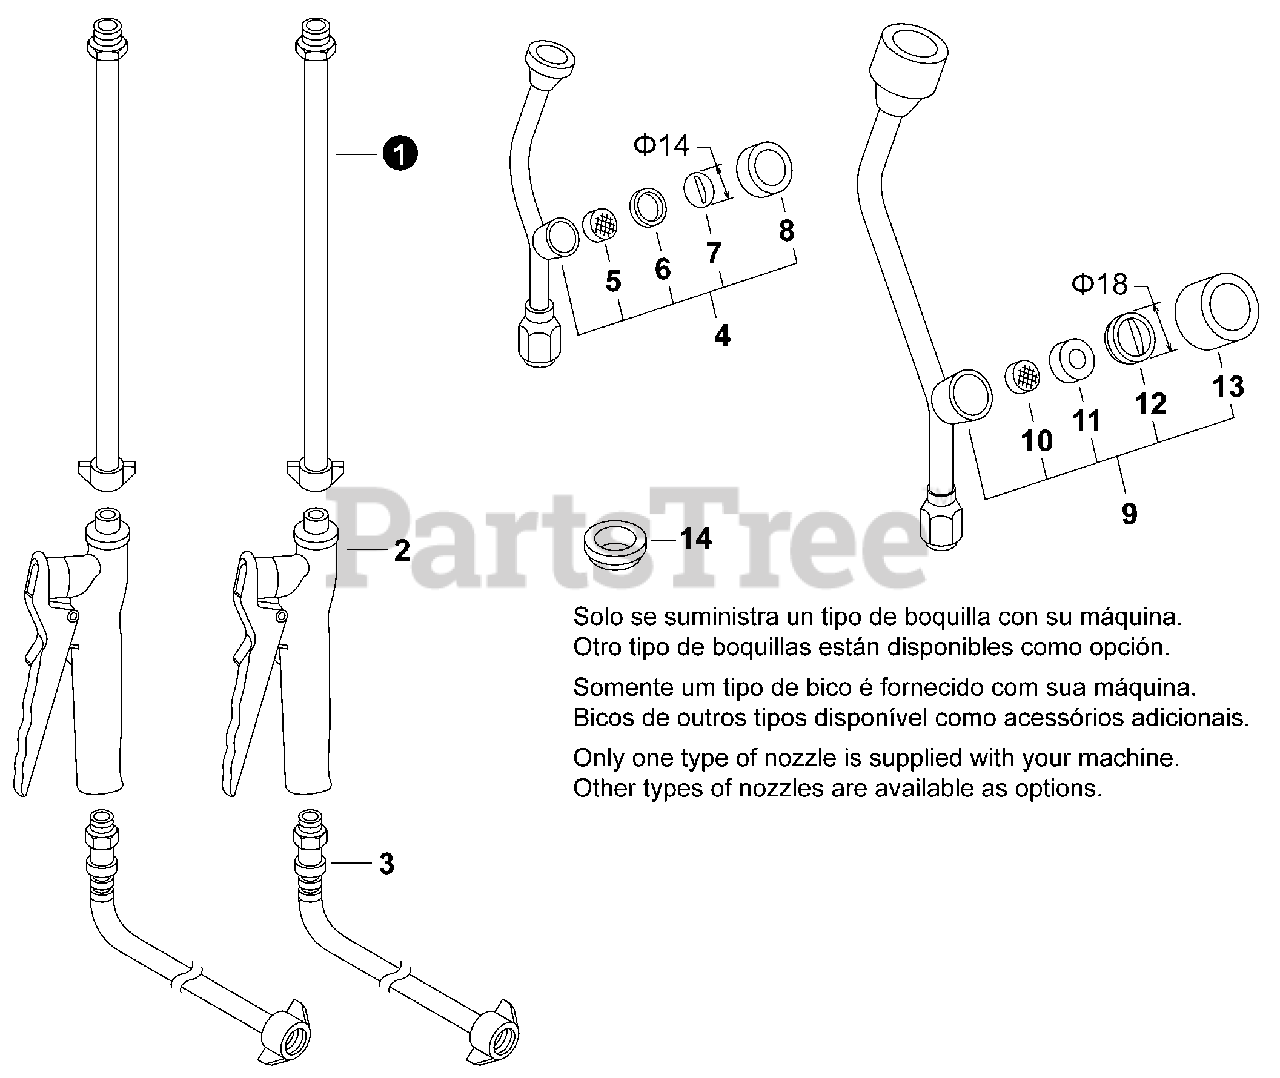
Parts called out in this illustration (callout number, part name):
1	WAND, SPRAYER
2	GRIP, WAND
3	HOSE ASSY, SPRAYER
4	NOZZLE, 2 HEAD METAL
7	NOZZLE J-5
8	CAP, NOZZLE
9	NOZZLE, 2 HEAD METAL
12	NOZZLE J-5 W/P
13	CAP, NOZZLE
14	ADAPTOR, TEE-JET? NOZZLE
